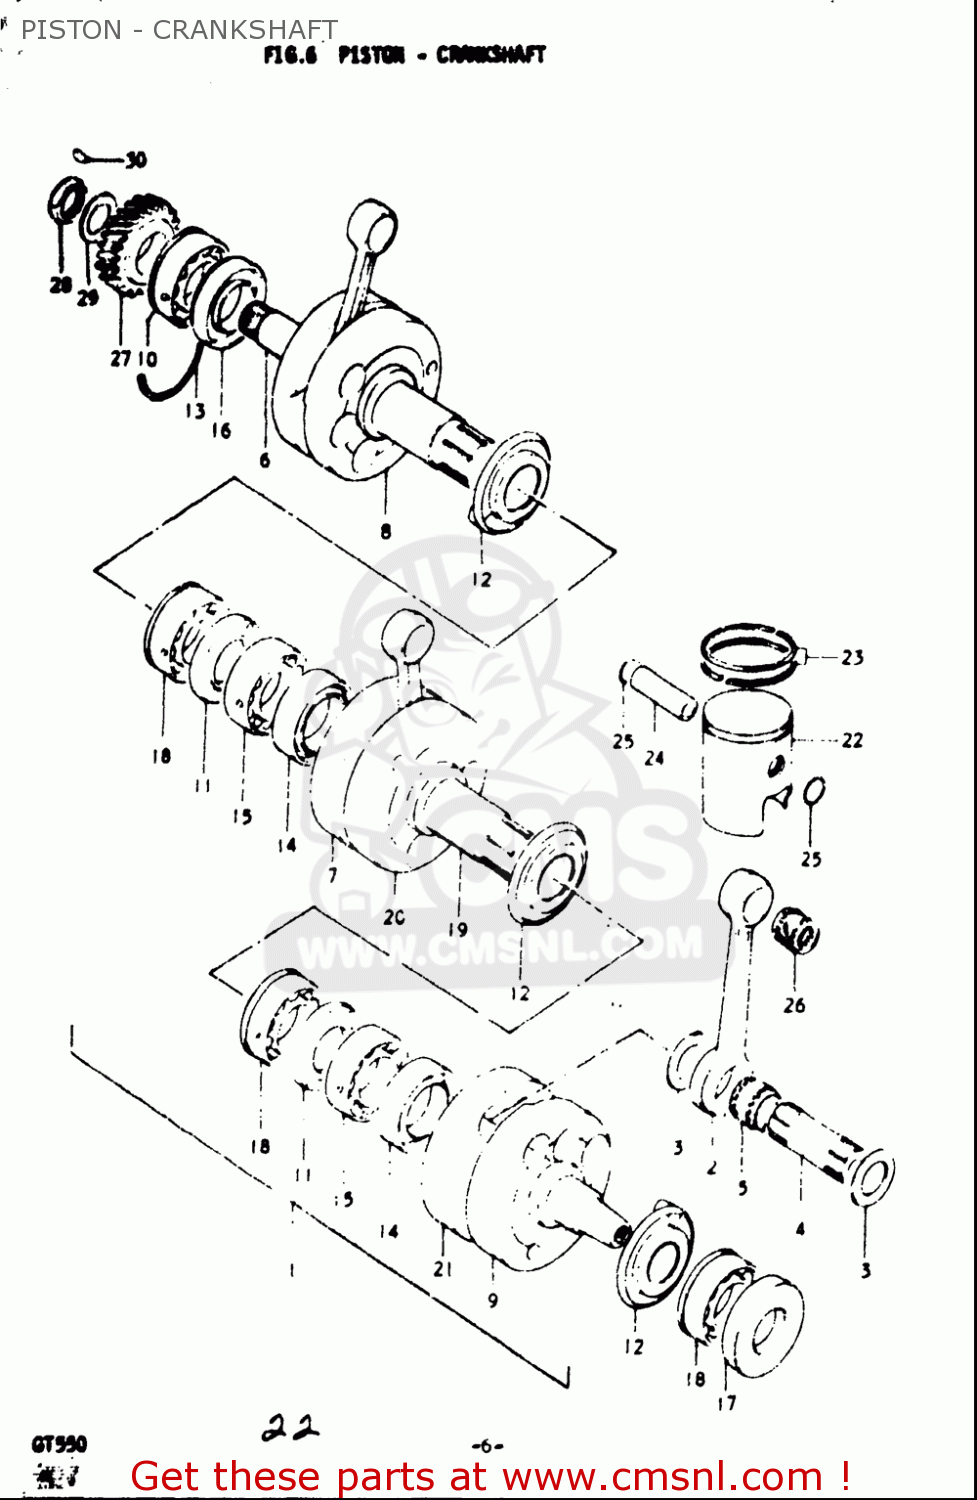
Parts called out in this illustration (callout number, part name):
3	WASHER(22X35X1)
4	PIN,CRANK
5	BEARING(22X28X16)
10	BEARING(25X62X17)
13	C RING
14	SEAL,OIL(38X62X10.5)
15	BEARING(25X62X17)
16	SEAL,OIL(32X62X8)
17	SEAL,OIL(25X62X9.9)
22	PISTON
23	RING SET,PISTON
24	PIN,PISTON
25	RING,SNAP 16MM
26	BEARING(16X21X19.6)
28	NUT (20MM)
29	WASHER
30	KEY
